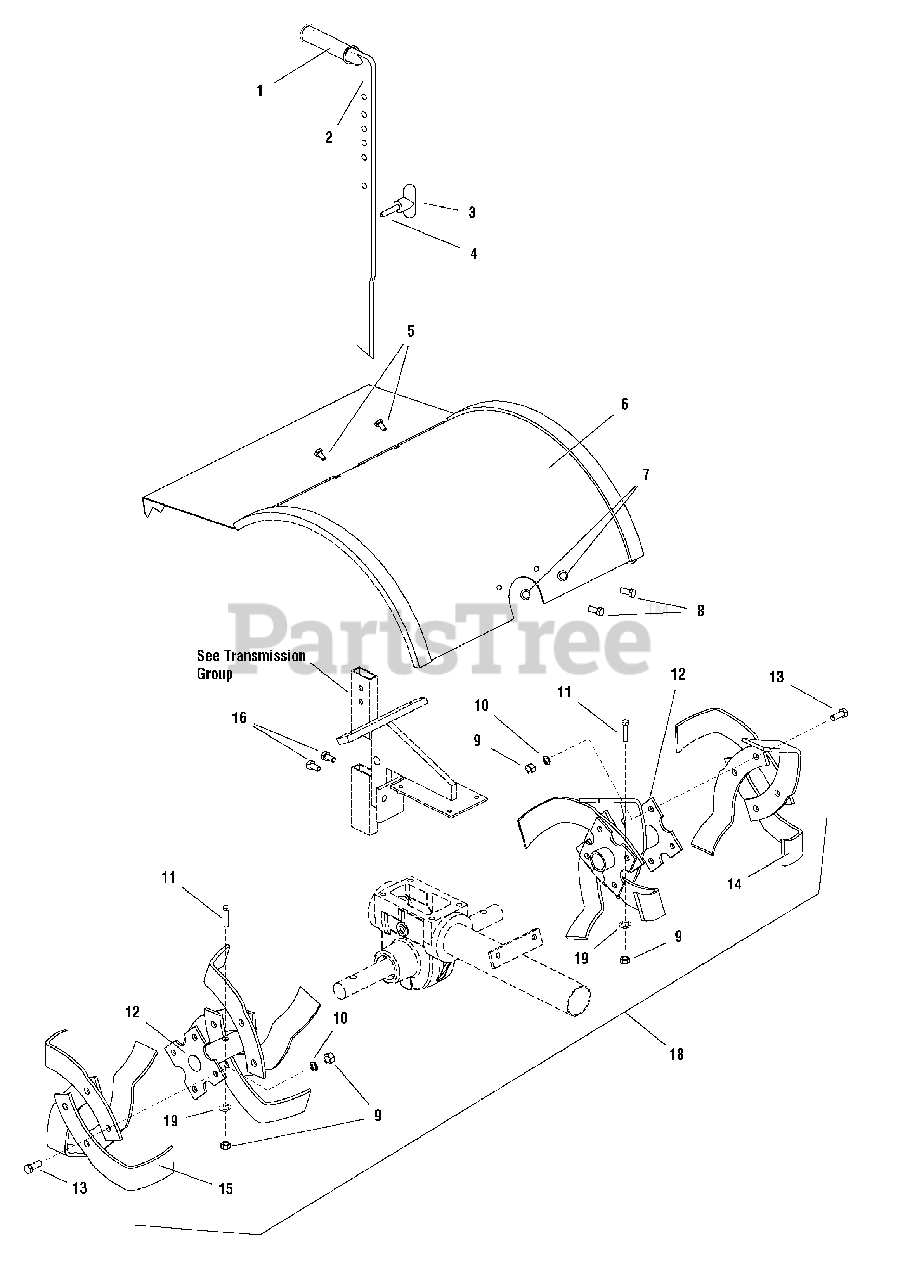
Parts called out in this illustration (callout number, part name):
1	HANDLE GRIP
2	LEVER, Drag Stake
3	KNOB, T Handle, Drag Stake
4	PIN, DETENT 5/16"-18 x 1"
5	CAPSCREW, Hex Head 1/4"-20 x 1/2" G5
6	HOOD, Tiller, No Decal
7	NUT, Hex Flange 5/16"-18 Two, Way Lock GA
8	CAPSCREW, Hex Head 5/16"-18 x 1/2" G5
9	NUT, Hex 3/8"-16NC, 2B
10	LOCKWASHER, Spring 3/8"
11	CAPSCREW, Hex Head 3/8"-16 x 1-3/4"
12	HOLDER, Tine Blade Left and Right
13	CAPSCREW, Hex Head 3/8"-16 x 1" G5
14	TINE BLADE, Left Side
15	TINE BLADE, Right Side
16	BOLT, Hex Flange Head 5/16"-18 x 1/2"
18	REPLACEMENT KIT, Tine Blade Holder & Tines
19	LOCKWASHER, Spring. 3/8
